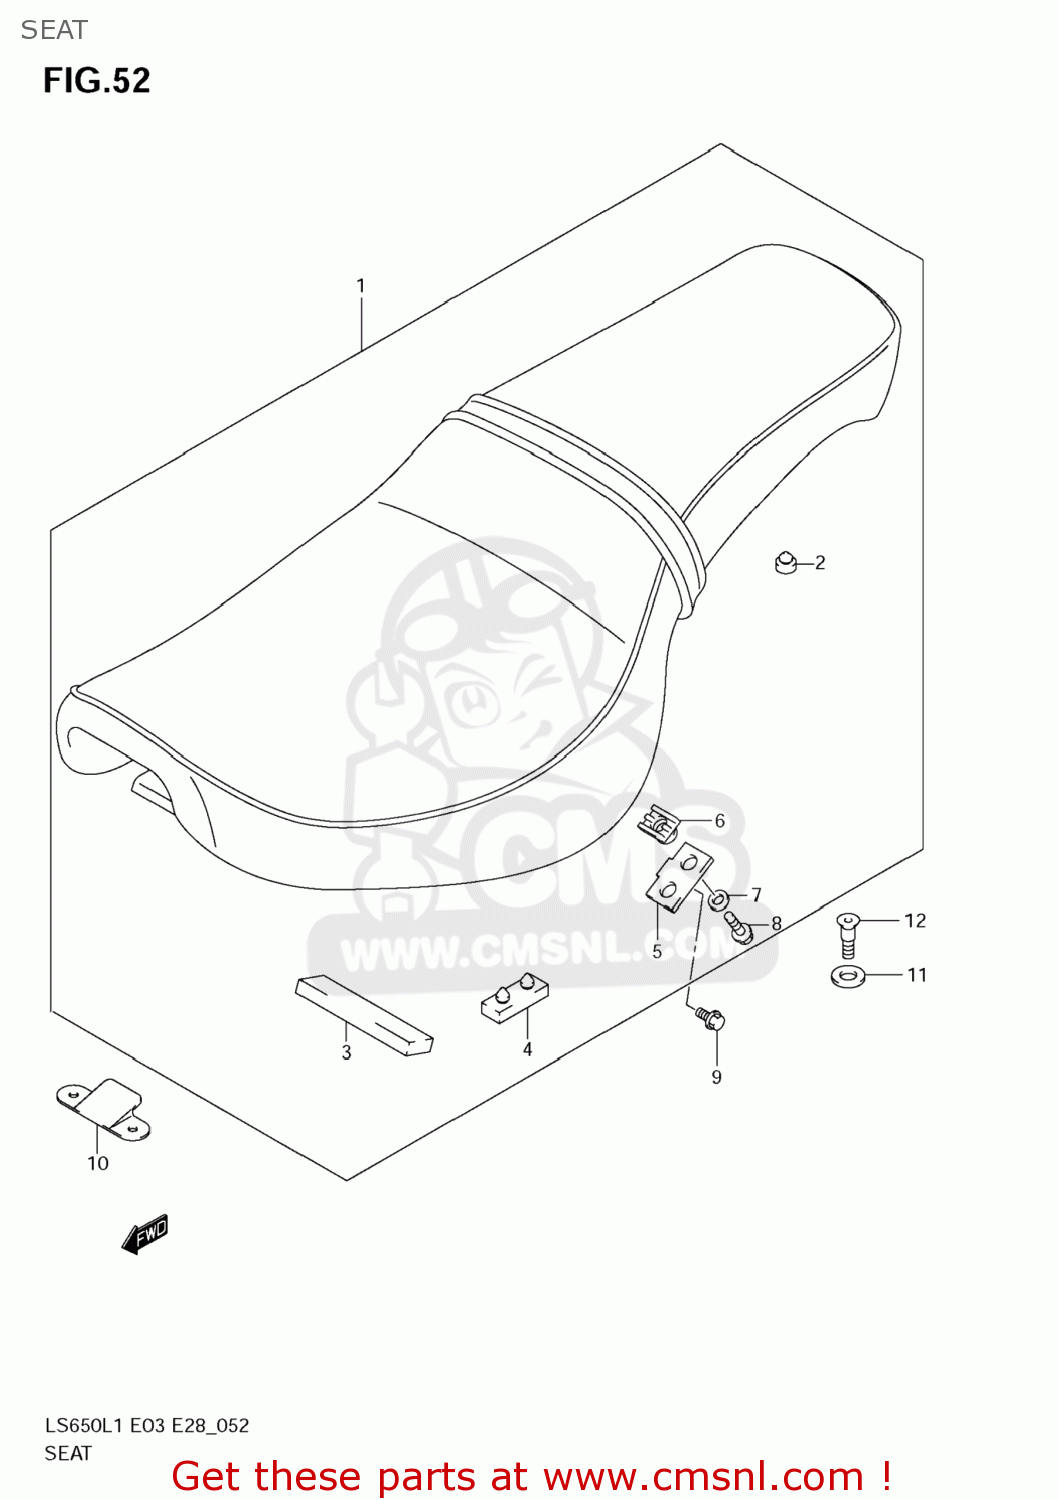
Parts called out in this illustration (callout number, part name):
1	SEAT ASSY
2	CUSHION,SEAT
3	CUSHION,CTR FR
4	CUSHION,SEAT
5	BRACKET,SEAT RR
6	CUSHION,SEAT RR BRACKET
7	WASHER(6.5X20X1.6)
8	BOLT
9	BOLT
10	PLATE,SEAT HOOK FR
11	CUSHION,SEAT RR
12	SCREW(6X12)
